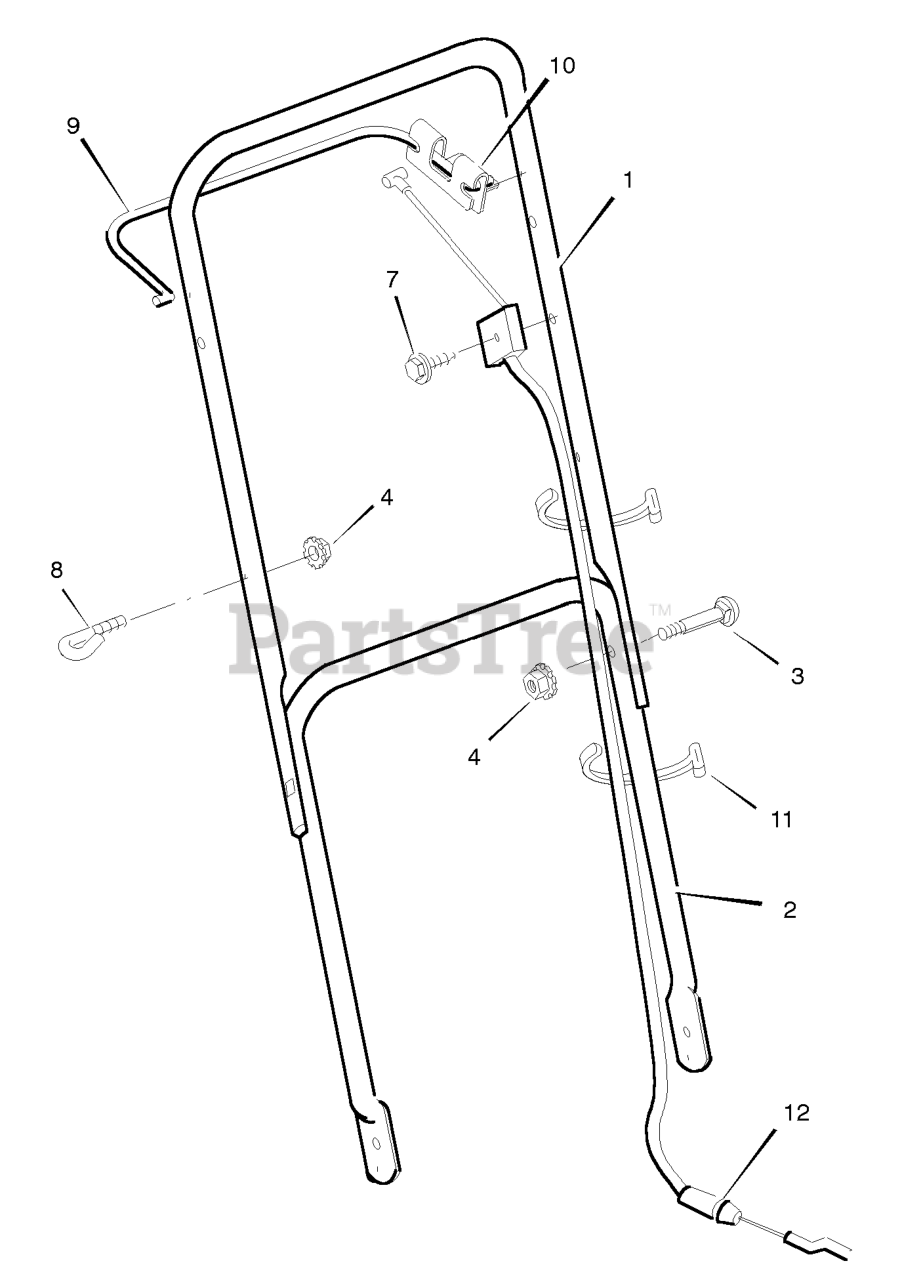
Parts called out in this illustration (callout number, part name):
1	Handle, Upper
2	Handle, Lower
4	Locknut
8	GUIDE, ROPE
9	Lever, Engine Stop
10	Bracket, Stop Lever
11	Fastener, Cable
12	Engine Stop Cable
